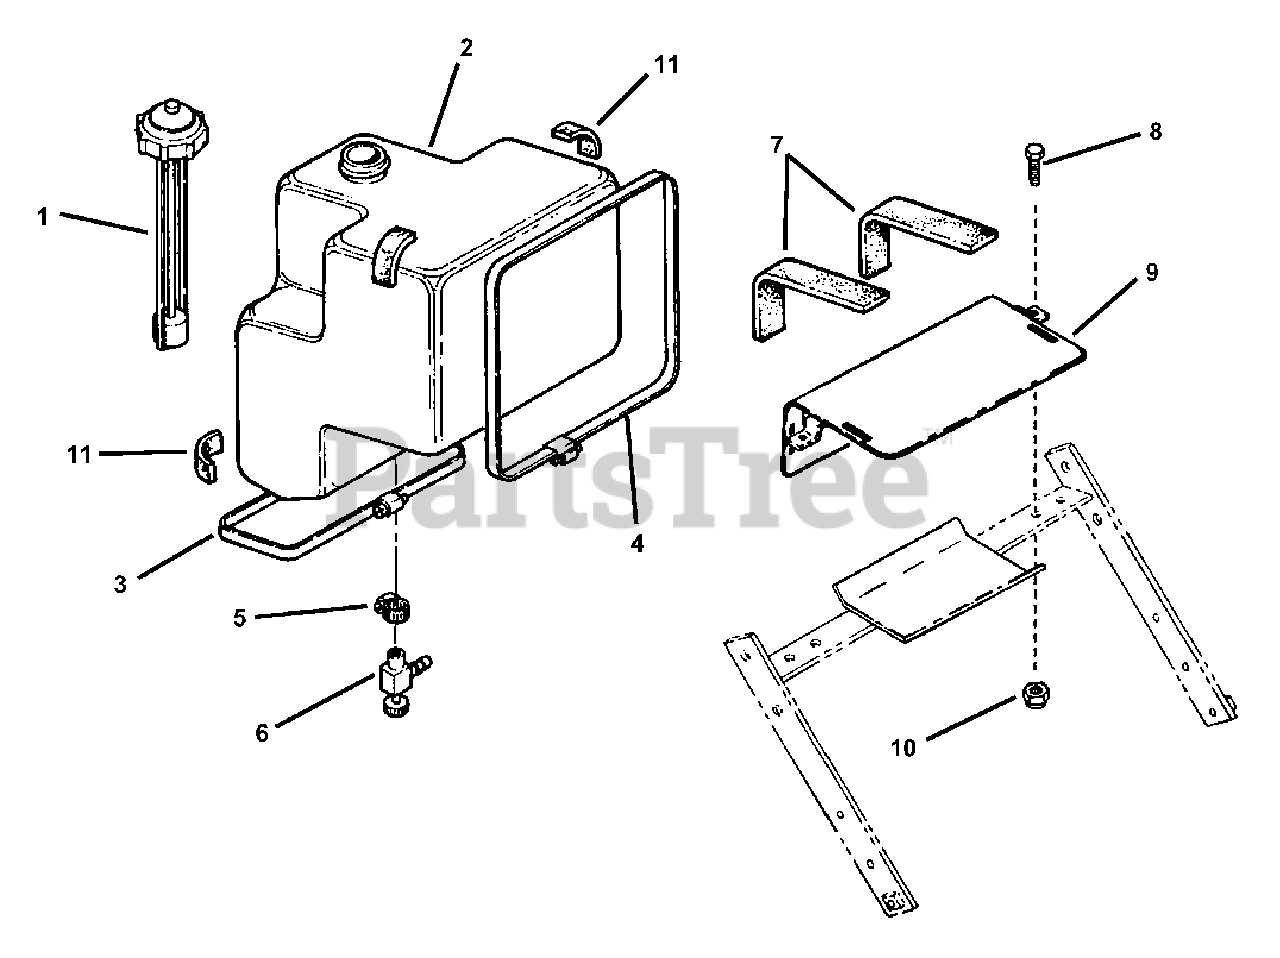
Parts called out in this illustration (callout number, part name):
1	GAS CAP w/Gage
2	GAS TANK w/Decals
3	TANK BAND, Short
4	TANK BAND, Long
5	CLAMP, Hose
6	SHUT-OFF, Gas Line
7	SADDLE PAD
8	SCREW, 3/8-16 x 1" Hex Head Cap, Grade 5
9	SADDLE, Retrofit
10	NUT, 3/8-16 Hex Nyloc
11	PAD, Gas Tank
